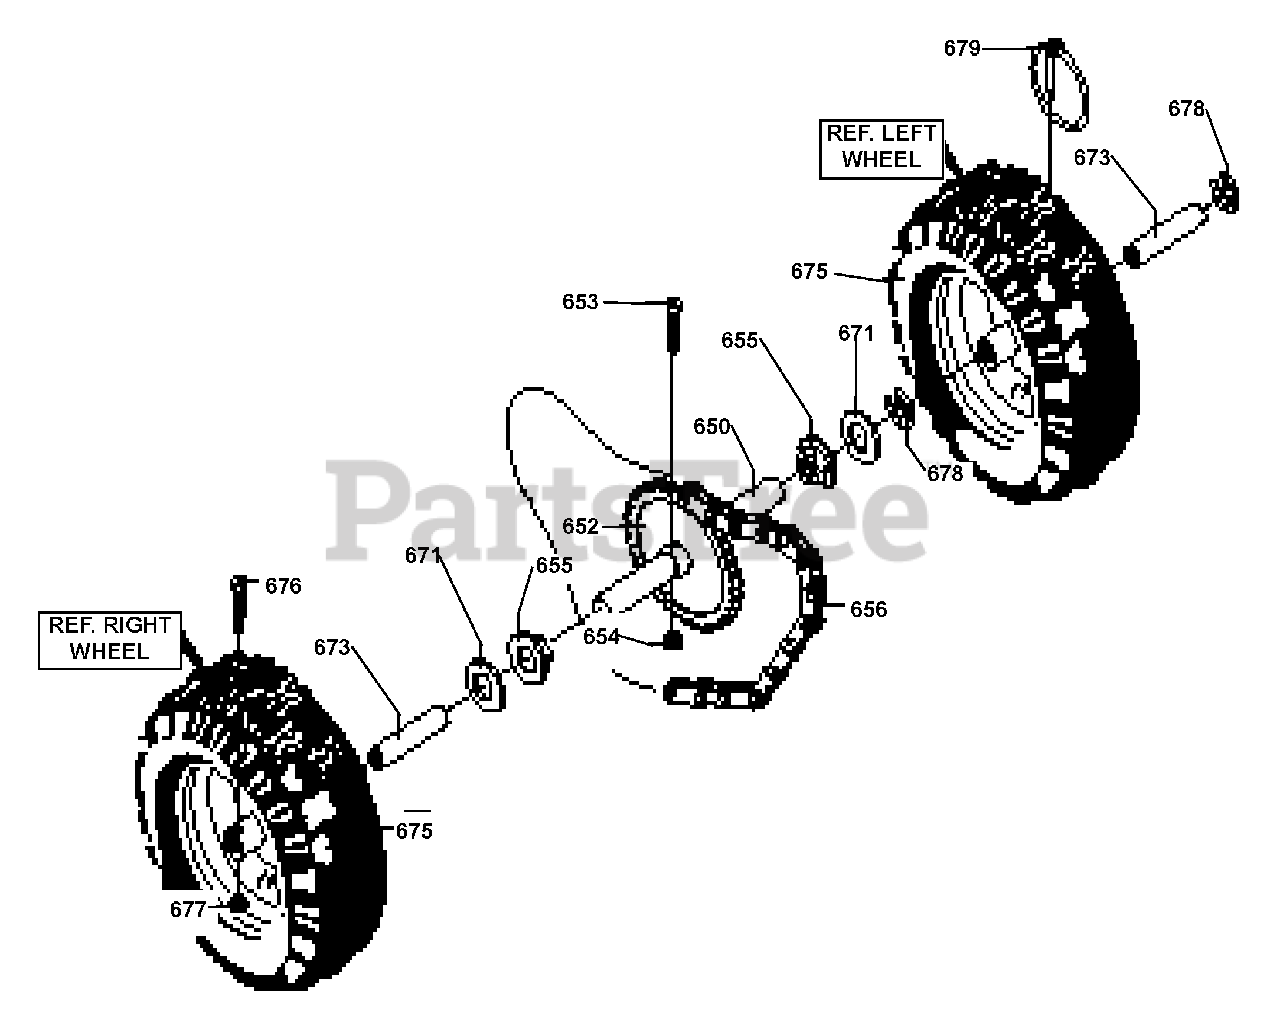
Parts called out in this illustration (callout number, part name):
650	SHAFT, AXLE
652	SPRKT & HUB, ASSY
653	SCREW, 1/4-20X2.25
654	NUT, 1/4-20
655	BEARING, FLANGE
656	CHAIN, ROLLER420X 41P
671	FLATWASHER
673	BUSHING, WHEEL 4"LG
675	TIRE & RIM
676	SCREW, SHR 1/4-20X1.75
677	NUT, 1/4-20
679	PIN, KLIK .25 X 1.38 DIA
